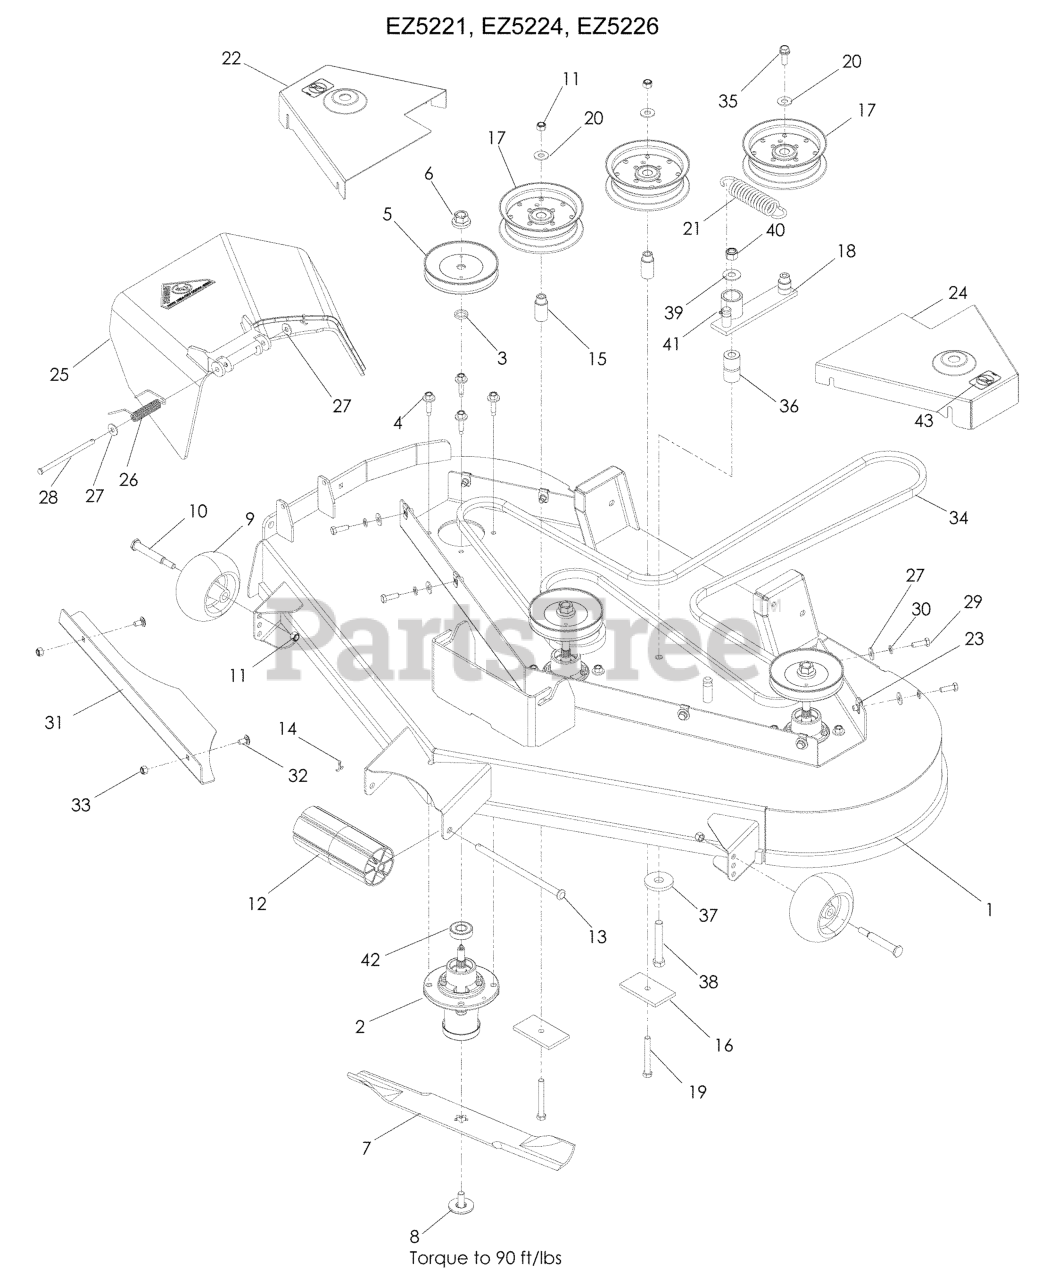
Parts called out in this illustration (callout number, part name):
1	DECK W/DECALS - EZ52
2	MANDREL.DECK.ASSEMBLY
3	WASHER-SPACER
4	WASHER HEAD SCREW
5	PULLEY
6	LOCKNUT - 9/16
7	BLADE, 18"
8	BLADE BOLT ASSY-7/16" TB REPL
9	GAUGE WHEEL
10	SHOULDER BOLT 1/2X2-5/8 ZD SPE
11	NUT 3/8-16 NYLOC
12	NOSE ROLLER 48"
13	NOSE ROLLER ROD
14	RP_COTTER PIN 1/8 X 3/4
15	IDLER BUSHING
16	SUPPORT PLATE
17	PULLEY, IDLER
18	PULLEY - IDLER, NYLON
19	HCS 3/8C X 3
20	WASHER 3/8 FLAT
22	BELT SHIELD, RIGHT 52, ORG
23	U-CLIP 5/16-18 NUT RETAINER
24	BELT SHIELD, LEFT 52, ORG
25	DISCHARGE CHUTE 52"
26	SPRING - TORSION
27	WASHER 5/16 FLAT
28	PIN-CLEVIS 5/16 DIA X 5.19 ZD
29	HCS 5/16C X 1
30	WASHER.LOCK.HVY.HLCL.SPR.5/16
31	CONFINEMENT PLATE, 52"
32	CARRIAGE BOLT 5/16C X 5/8"
33	NUT 5/16 NYLOC
34	BELT, DECK
35	4CS 3/8C X 1 SERRATED HEAD
36	PIVOT BUSHING
37	WASHER, SUPPORT
38	HCS 1/2C X 3 1/4
39	WASHER 1/2 FLAT
40	NUT 1/2-13 HEX NYLOC ZD
41	ZERK
42	BEARING, BALL
43	DECAL, NO STEP
